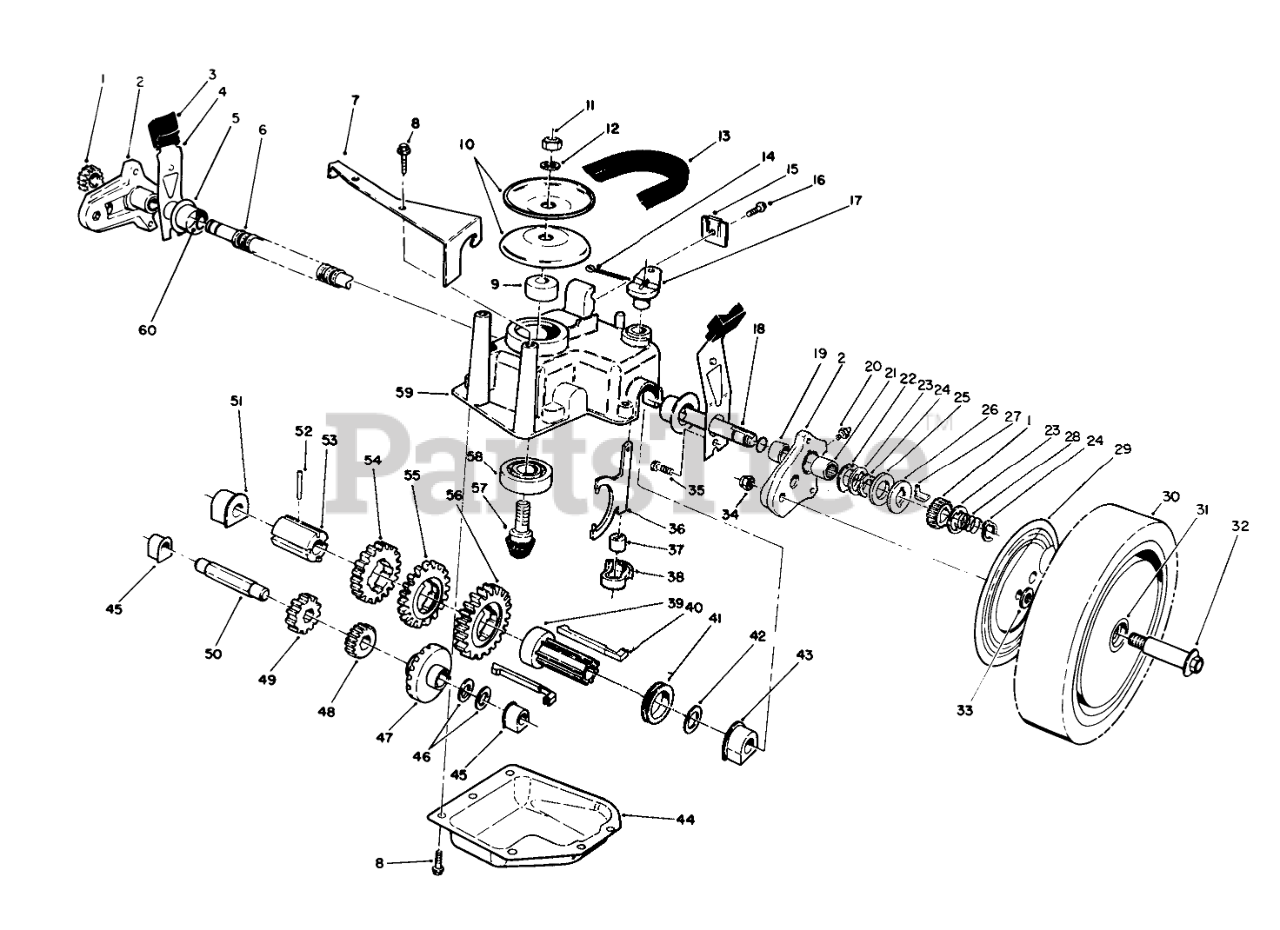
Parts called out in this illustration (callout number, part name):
1	GEAR-PINION
2	Pivot Arm Assembly (Incl. Ref. #19, 20, 21)
3	KNOB-ARM
4	SPRING ARM ASM SP
5	CAP-END
6	CONDUIT-CONVOLUTED, SPLIT
7	Bracket-Guide
8	SCREW-HWHTF
9	SPACER
10	Pulley Half
11	NUT-HEX
12	WASHER-FLAT
13	V-BELT E
14	PIN-COTTER
15	Cable Clamp
16	SCREW-HWHTF
17	SHIFT LEVER
18	SHAFT-OUTPUT
19	BUSHING
20	FITTING-GREASE
21	BEARING-ROLLER
22	WASHER-ARM, PIVOT
23	WASHER-THRUST, KEYED
24	RING-CLIP, LOCKING
25	RING-FRICTION
26	WASHER-CLUTCH
27	KEY-ROCKING, LH
28	SPRING-COMPRESSION
29	WHEEL COVER
30	Wheel-Tire 8 Gear Assembly (Incl. Ref. #31)
31	HOC ADJUSTMENT ASM
32	WHEEL BOLT
33	WASHER
34	Nut
35	Screw
36	YOKE-SHIFT
37	BUSHING-YOKE
38	RETAINER-FORK, SHIFT
39	Sleeve-Shift Key
40	Key Shift
41	SHIFT COLLAR
42	WASHER-PLAIN
43	BUSHING-OUTPUT
44	Cover-Gearcase
45	BUSHING
46	WASHER-THRUST
47	Gear-Bevel
48	PINION-20T
49	PINION-25T
50	SHAFT-INTERMEDIATE
51	BUSHING
52	PIN-SPRING
53	SLEEVE-GEAR
54	GEAR-39T
55	GEAR-44T
56	GEAR-49T
57	Gear-Pinion
58	BEARING-BALL
59	CASE-GEAR, UPPER
60	O-RING
